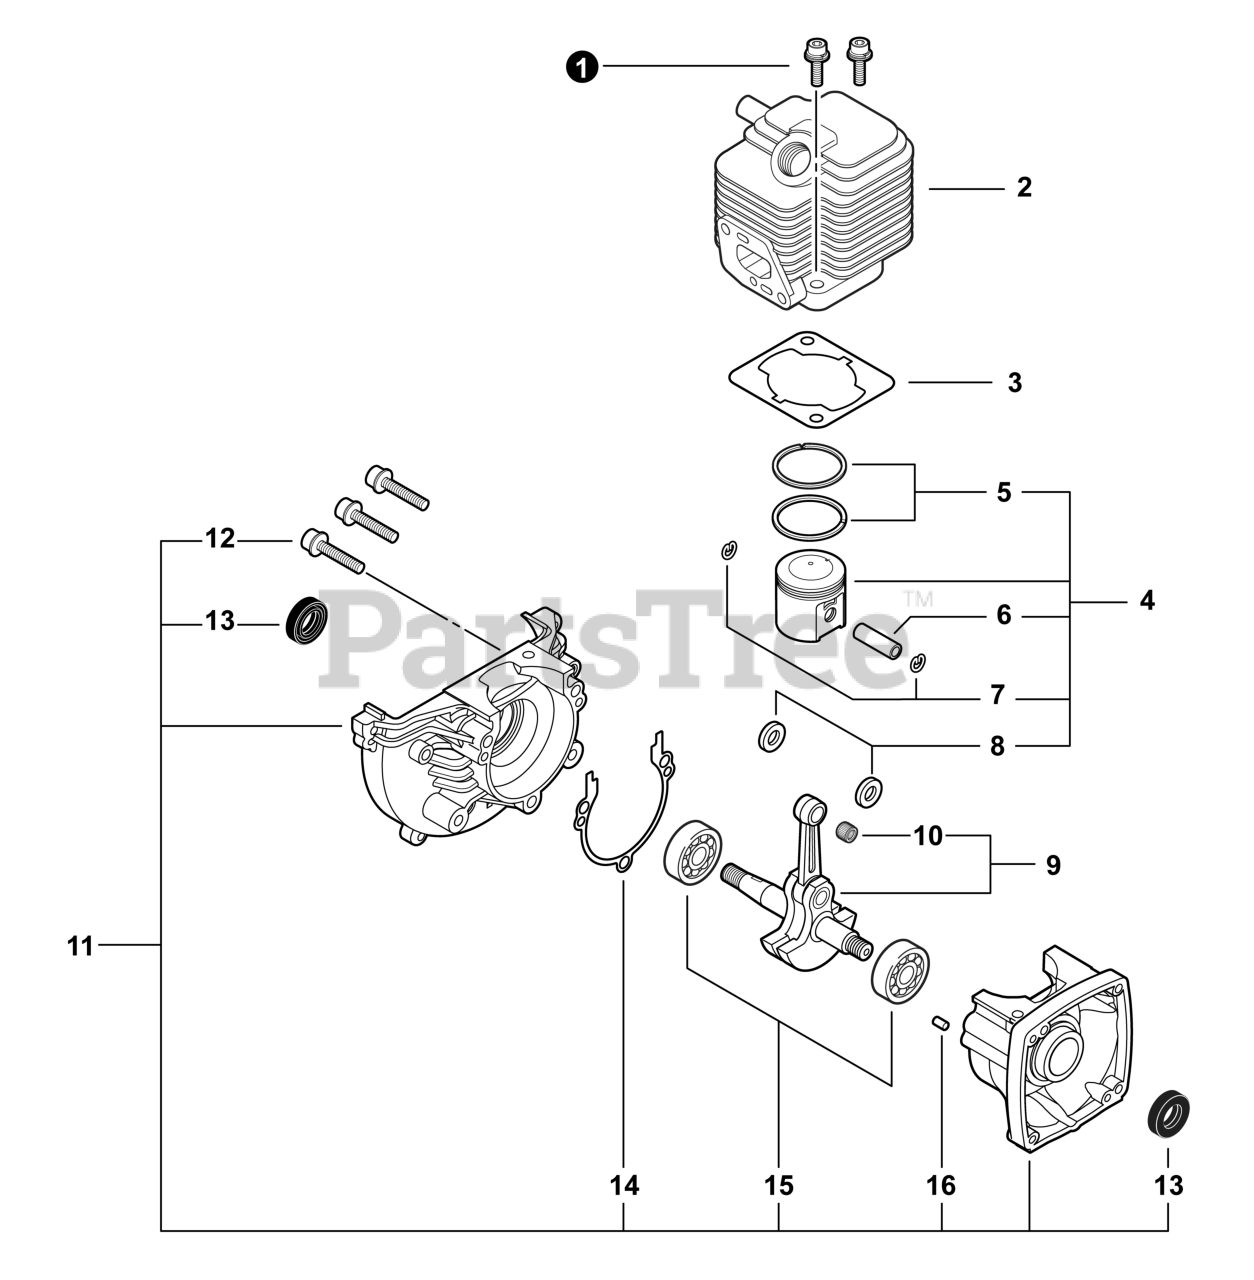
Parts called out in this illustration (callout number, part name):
1	BOLT 5x22
2	CYLINDER
3	GASKET, CYLINDER
4	PISTON KIT
5	RING, PISTON
6	PIN, PISTON 8
7	RING, SNAP
8	WASHER 8.2x13x0.8
9	CRANKSHAFT ASSY
10	BEARING, NEEDLE 8
11	CRANKCASE KIT
12	BOLT 5x28
13	SEAL, OIL 12
14	GASKET, CRANKCASE
15	BEARING, BALL 6201
16	PIN, LOCATING 4x8
